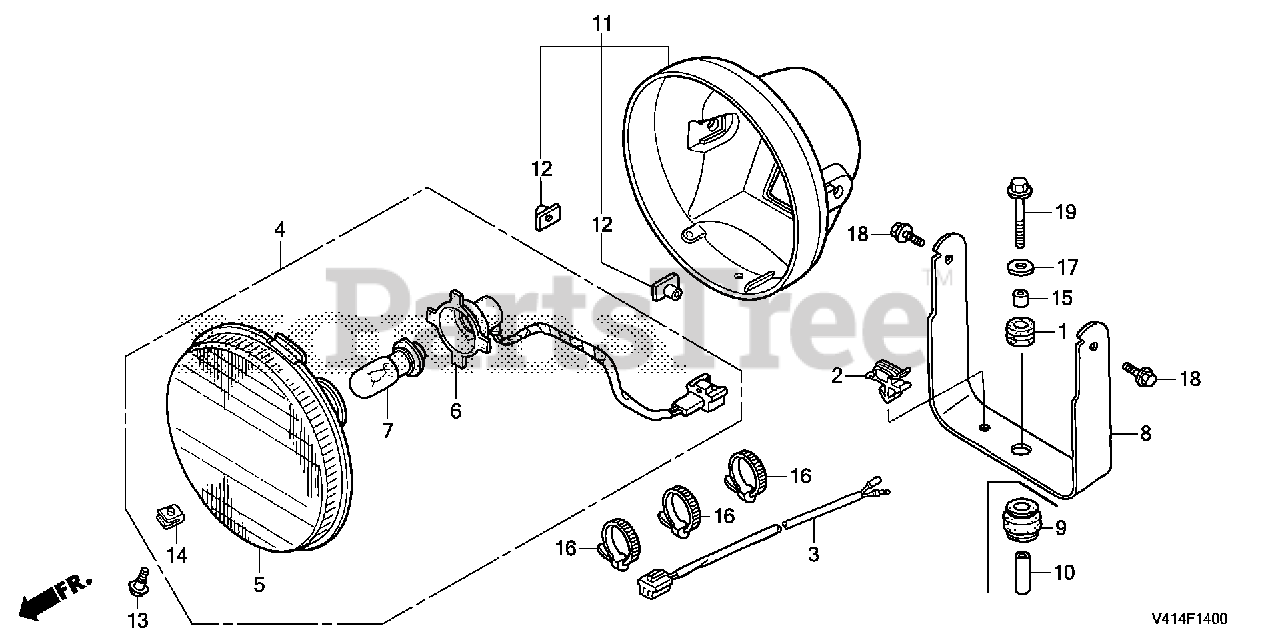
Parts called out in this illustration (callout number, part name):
1	GROMMET, OIL COOLER
2	CLIP, WIRE HARNESS
3	WIRE ASSY., WORK LIGHT
4	HEADLIGHT ASSY.
5	HEADLIGHT UNIT
6	SOCKET ASSY., HEADLIGHT
7	BULB, HEADLIGHT (12V 15/15W)
8	BRACKET, HEADLIGHT
11	CASE ASSY., HEADLIGHT
12	NUT, SPECIAL (6X7)
13	SCREW, PAN (5X16)
14	NUT, SPRING (5MM)
15	COLLAR, RR. TURN SIGNAL MOUNTING
16	BAND, WIRE (95MM)
17	WASHER, PLAIN (8MM)
18	BOLT, FLANGE (6X12)
19	BOLT, FLANGE (8X30)
